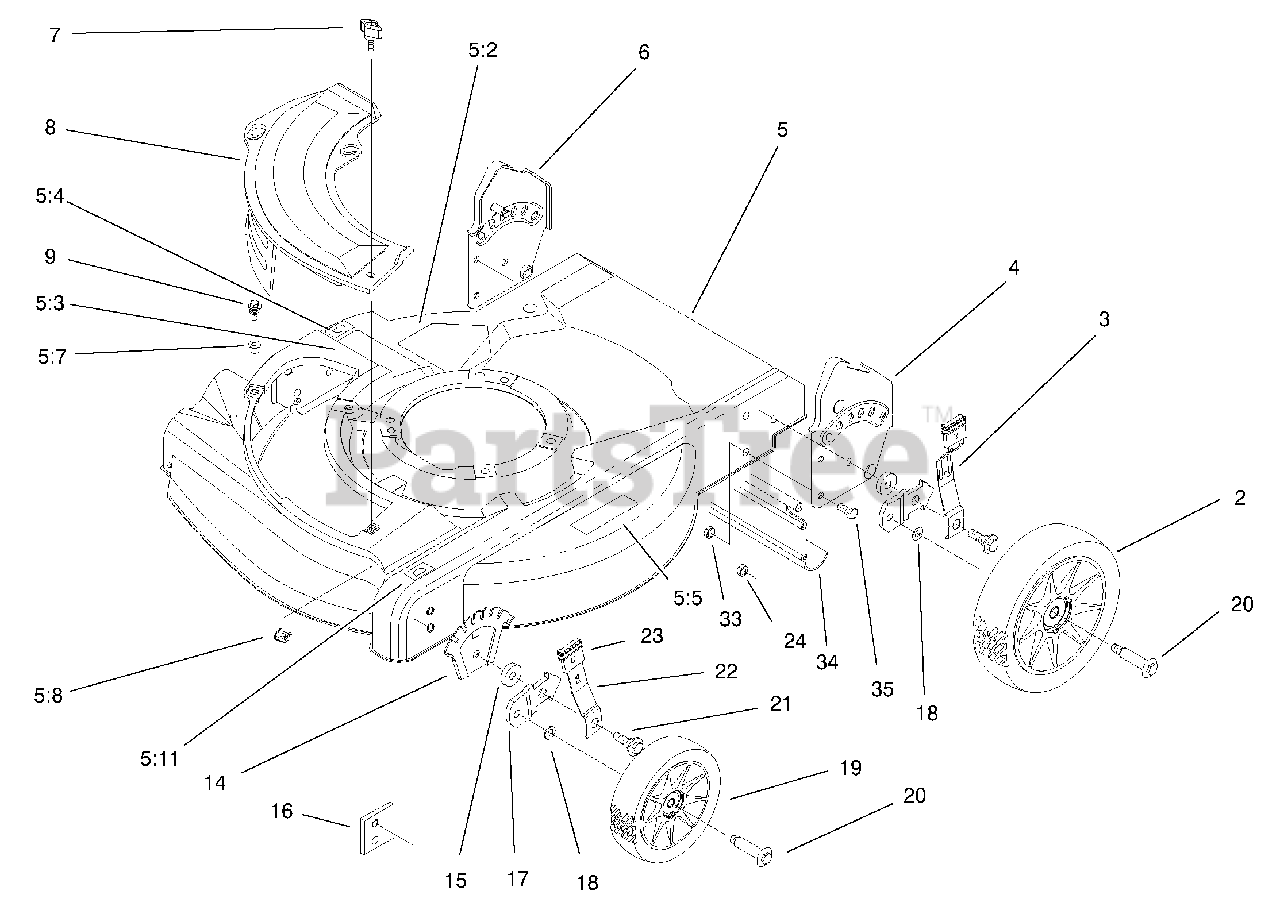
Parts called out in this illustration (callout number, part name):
3	Spring Arm ASM-Rear
4	LH Handle Brkt ASM
5	ASM-Hsg/Baffle w/Decals
5:2	Decal-Danger
5:3	Decal-Warning
5:4	Decal-HOC R
5:5	Decal-Safety Instruct
5:7	Grommet-Plastic
5:8	Nut-Cage
5:11	Decal-HOC L
6	RH Handle Brkt ASM
8	Plate-Mulch
9	Screw-Sems
14	Plate-Hght Adj
15	Washer-Wheel
16	Plate-Baffle
17	Bracket-Wheel Height Adj.
18	Washer-Bolt, Wheel
20	Bolt-Shoulder
21	Bolt-Shoulder
22	Arm-Front Spring
23	Knob-Height Adj. Lever
24	Nut-Lock, NI
33	Nut-Lock,NI
34	Shield-Trailing
35	Screw-HH
